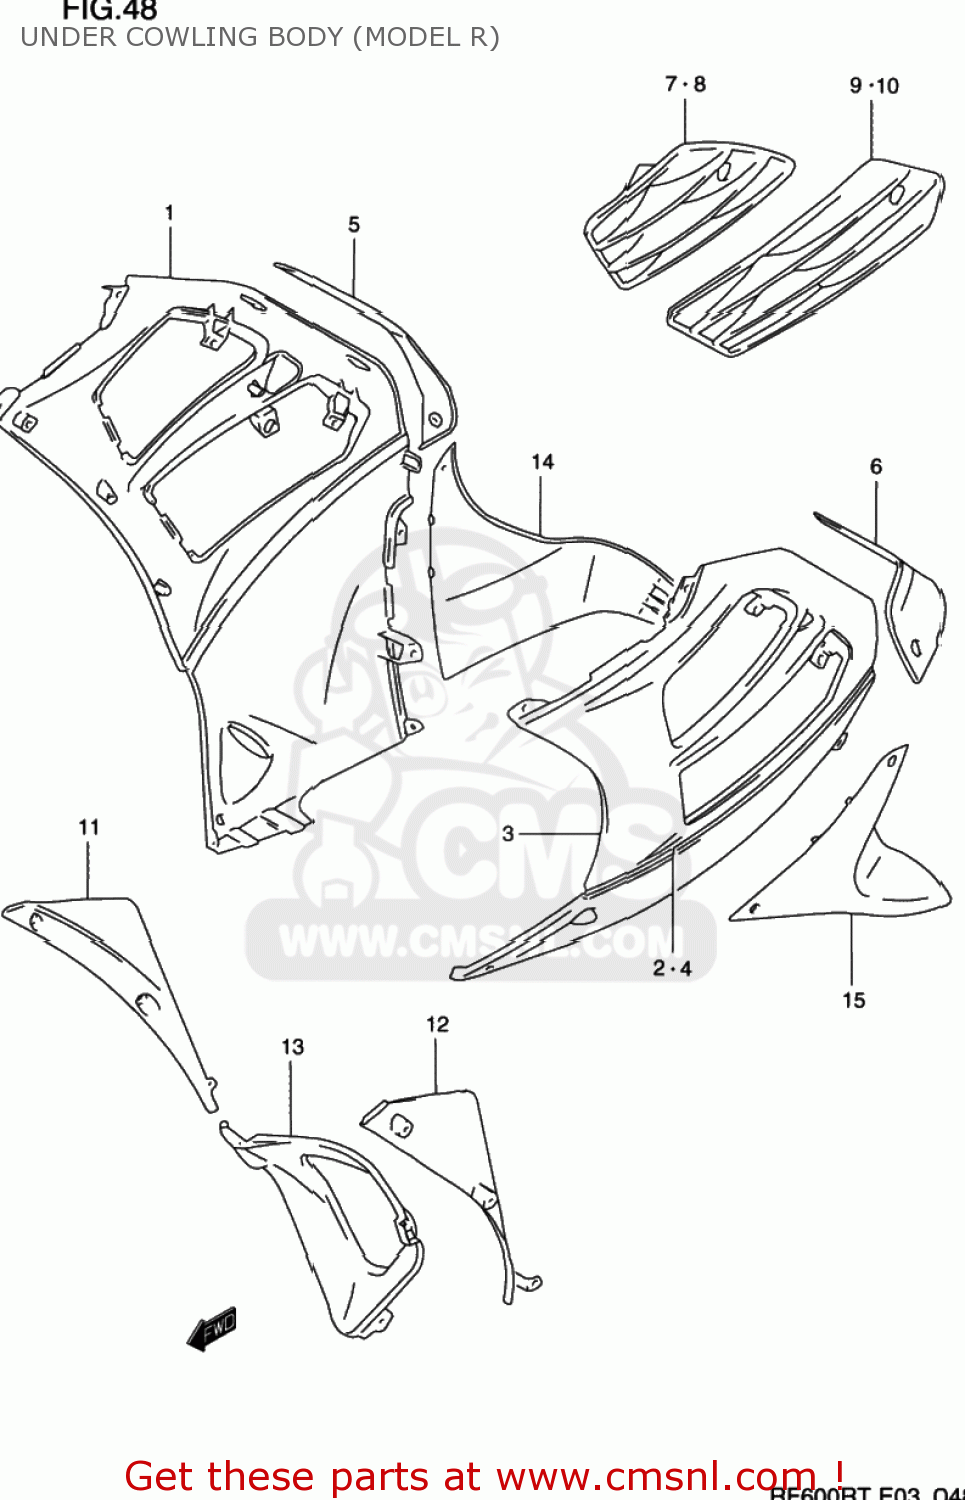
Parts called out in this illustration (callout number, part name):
1	COWLING ASSEMBLY,UNDER,RIGHT (R
2	TAPE,UNDER COWL,R
3	COWLING ASSY,UNDER,L(RED)
4	TAPE,UNDER COWL
5	PANEL,UNDER RH
6	PANEL,UNDER,L
7	COVER,UNDER COWLING,UPPER,RIGHT (
8	COVER,UNDER COWL UPR,L
9	COVER COMP,UNDER COWLING
10	COVER,UNDER COWLING,LOWER,LEFT
11	COWLING,UNDER INNER,R
12	COWLING,UNDER INNER,L
13	COWLING,UNDER CTR
14	COWLING,UNDER RR,R
15	COWLING,UNDER RR,L
